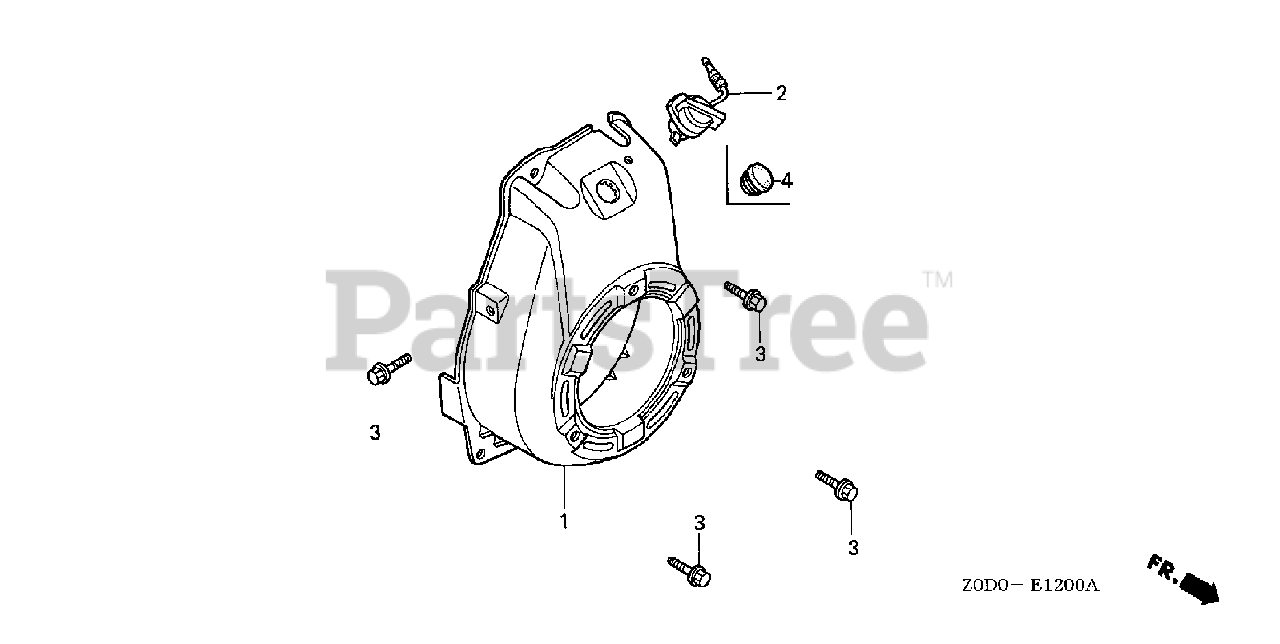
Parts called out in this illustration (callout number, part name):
1	COVER, FAN *R8* (BRIGHT RED)
1	COVER, FAN *NH1* (BLACK)
2	SWITCH ASSY., ENGINE STOP
3	BOLT, FLANGE (6X14)
